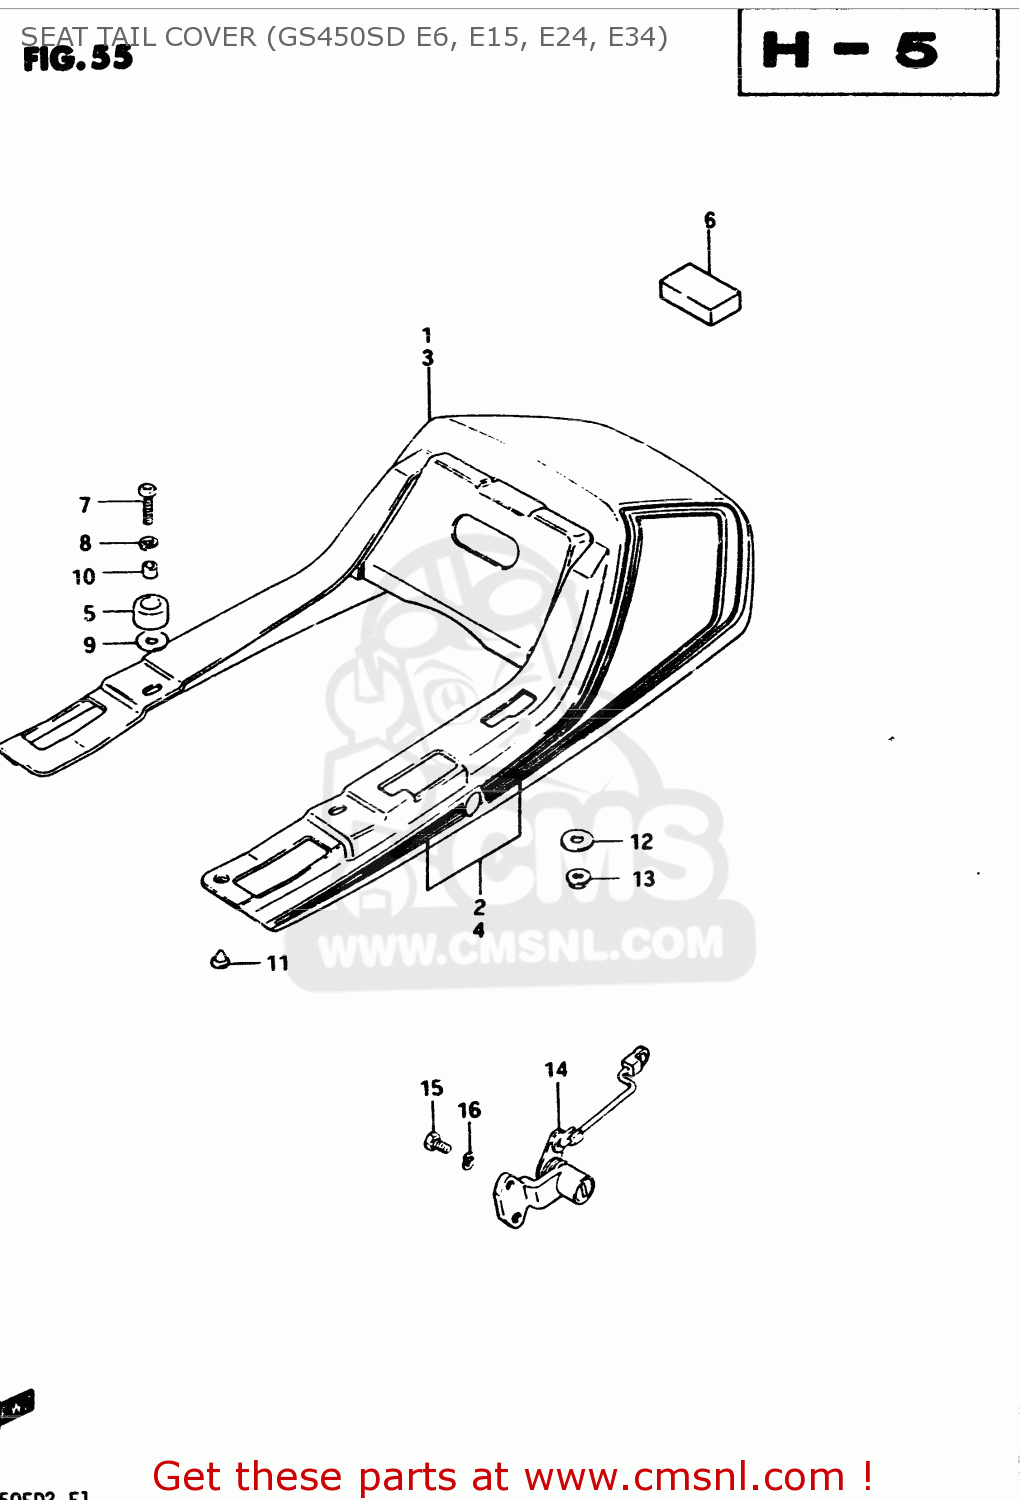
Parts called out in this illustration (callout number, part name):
1	TAIL COVER, SEAT (WHITE)
2	TAPE SET, SEAT TAIL COVER
3	TAIE COVER, SEAT (BLACK)
4	TAPE SET, SEAT TAIL COVER
5	CUSHION,COVER
6	CUSHION
7	SCREW
8	LOCK WASHER
9	WASHER (6.5X24X1.6)
10	SPACER
11	CUSHION
12	WASHER
13	NUT 6MM
14	LOCK ASSEMBLY,SEAT
15	BOLT 5X10
16	LOCK WASHER
